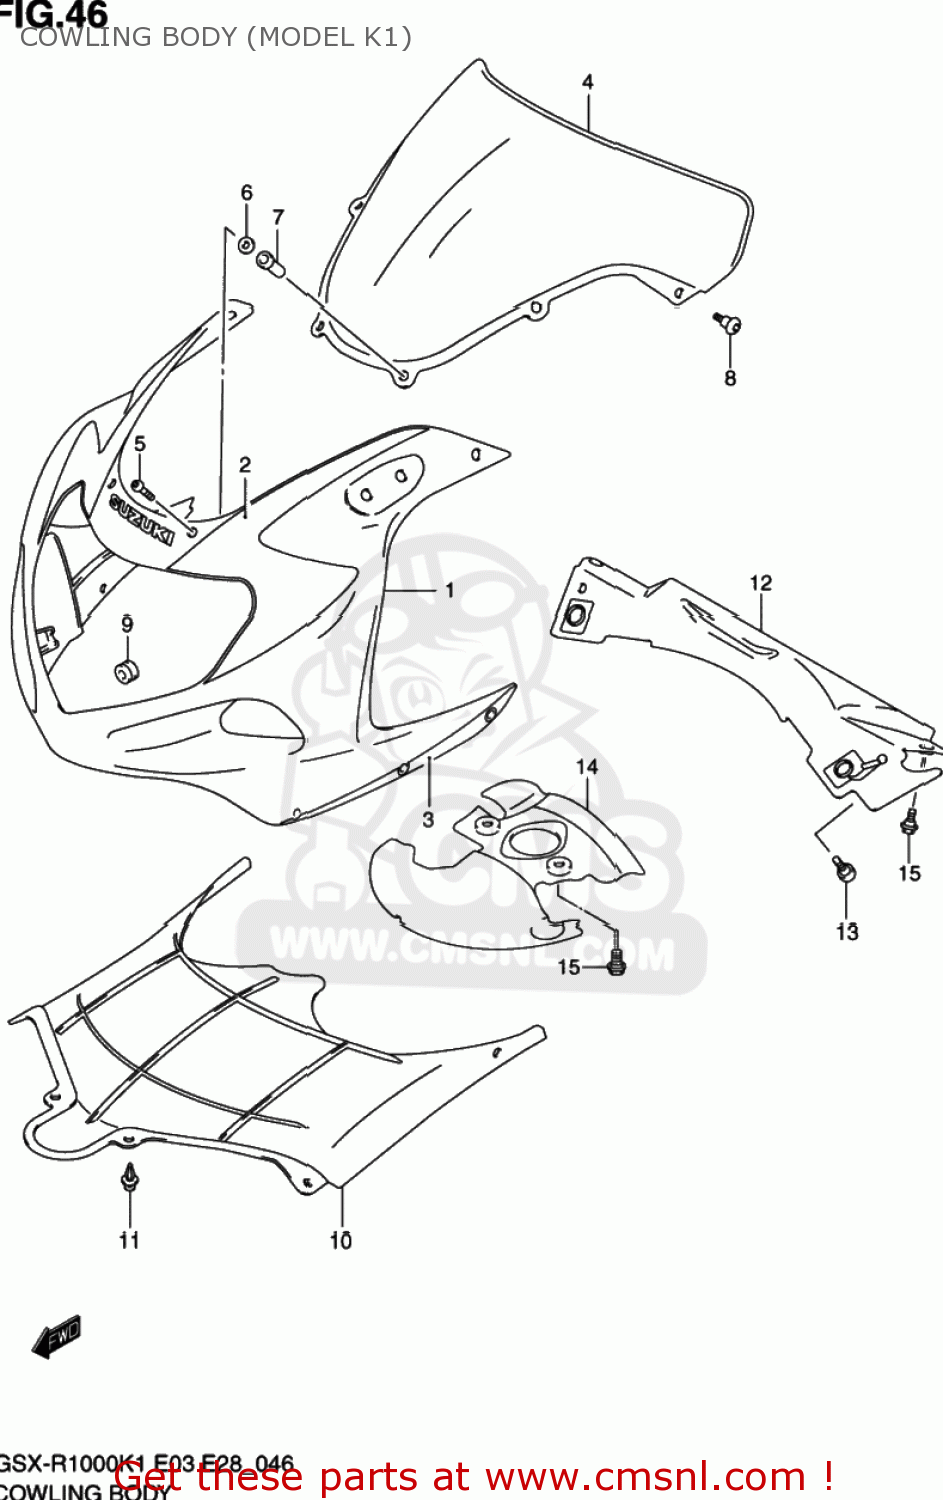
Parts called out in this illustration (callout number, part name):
1	COWLING,BODY(RED)
2	TAPE,COWL BODY FR
3	TAPE,COWL BODY SIDE
4	WINDSCREEN
5	SCREW(5X14)
6	WASHER
7	NUT
8	SCREW(5X16)
9	CUSHION
10	COVER,BODY COWLING
11	CLIP(BLACK)
12	COVER,COWLING FR LWR
13	SCREW(5X13)
14	COVER,LWR BRACKET
15	BOLT
